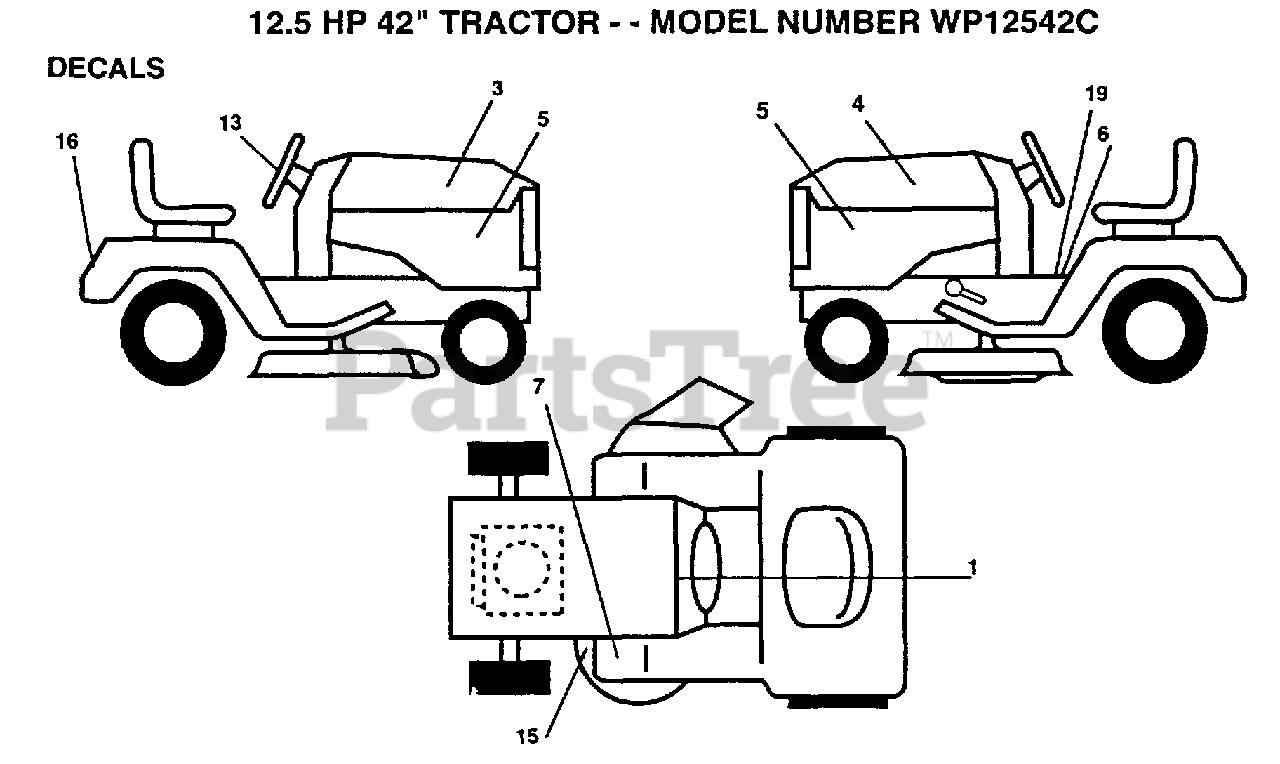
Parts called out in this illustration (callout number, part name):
1	DECAL.DASH.INST.
3	DECAL.HOOD.RH
4	DECAL.HOOD.LH
6	DECAL
13	DECAL, INSERT
15	DECAL.V.BELT
16	DECAL, FENDER LOGO
19	DECAL BRAK PARK
